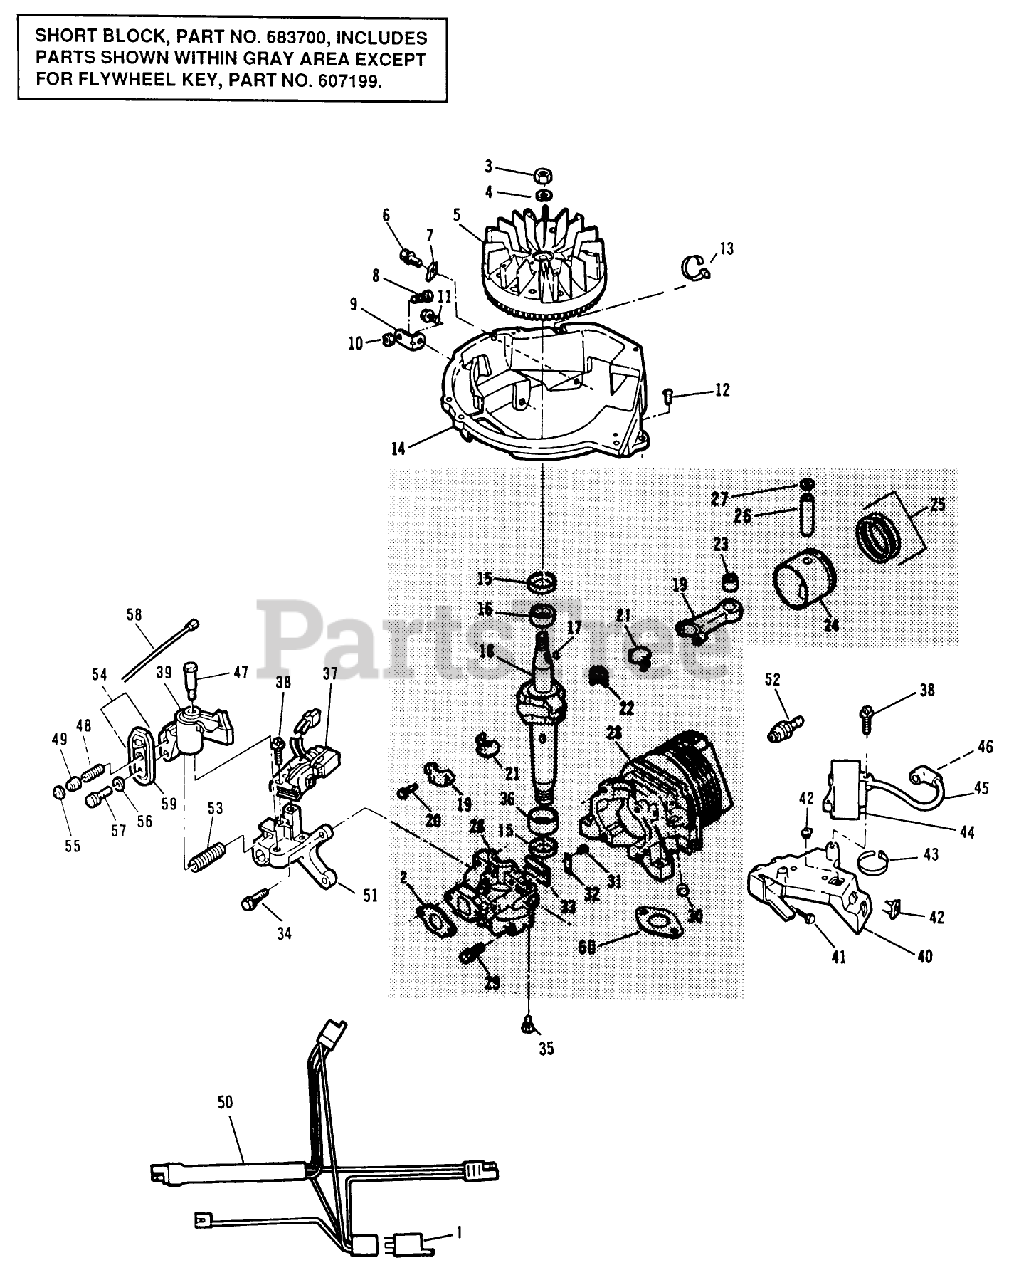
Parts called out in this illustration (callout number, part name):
2	GASKET CARB S
5	FLYWHEEL ASSY F
6	SCREW-SEMS
8	BOLT F
10	NUT-LOCK F
12	SCREW F
14	BASE SHROUD F
15	SEAL-OIL
16	BEARING V
20	SCREW-HSH
21	LINER ASM
22	BEARING-NEEDLE
23	BEARING AY F
27	RING-RETAINING
29	SCREW-H.W.HD. F
30	PLUG-CORE VF
31	SCREW-HH
32	PLATE-BACKUP, REED
36	BEARING V
37	ALTERNATOR AY F
40	C.D. BRKT F
42	NUT-CLIP
45	HT LEAD&COVER XEV
49	ACTUATOR-LEVER, BRAKE
51	BRACKET F
51	BRACKET-BRAKE F
53	SPRING-BRAKE
55	RETAINER S
57	SCREW-SEMS
58	WIRE LEAD AY F
